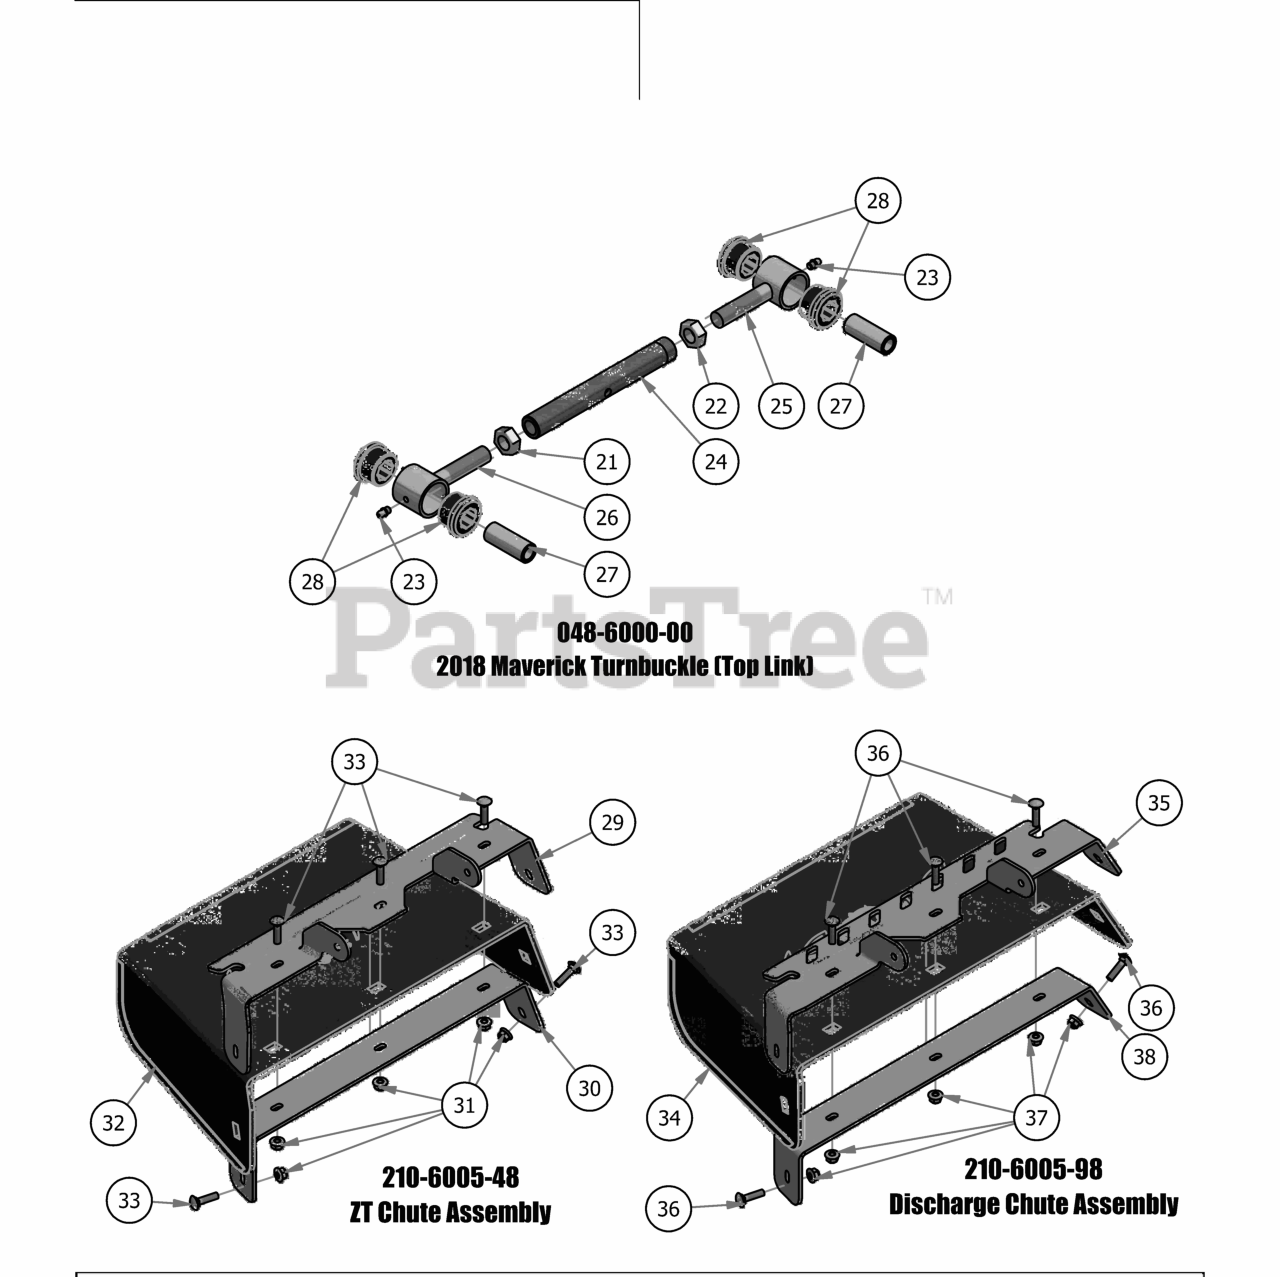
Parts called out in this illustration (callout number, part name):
21	NUT, 5/8-18
22	NUT, 5/8-18LH
23	1/4-28 Grease Fitting
24	2018 Maverick Toplink Body
25	2018 Maverick Bushing Retainer Left-Handed
26	2018 Maverick Bushing Retainer Right-Handed
27	2018 Maverick Bushing Sleeve
28	2018 Maverick Bushing
29	Discharge Upper Chute Bracket
30	Discharge Lower Chute Bracket
31	5/16" Nylon Flange Nut
32	Rubber Discharge Chute
33	5/16" x 1 1/4" Carriage Bolt
34	Rubber Discharge Chute
35	60" Discharge Chute Upper Hanger
36	5/16" x 1 1/4" Carriage Bolt
37	5/16" Nylon Flange Nut
38	60" Discharge Lower Bracket
